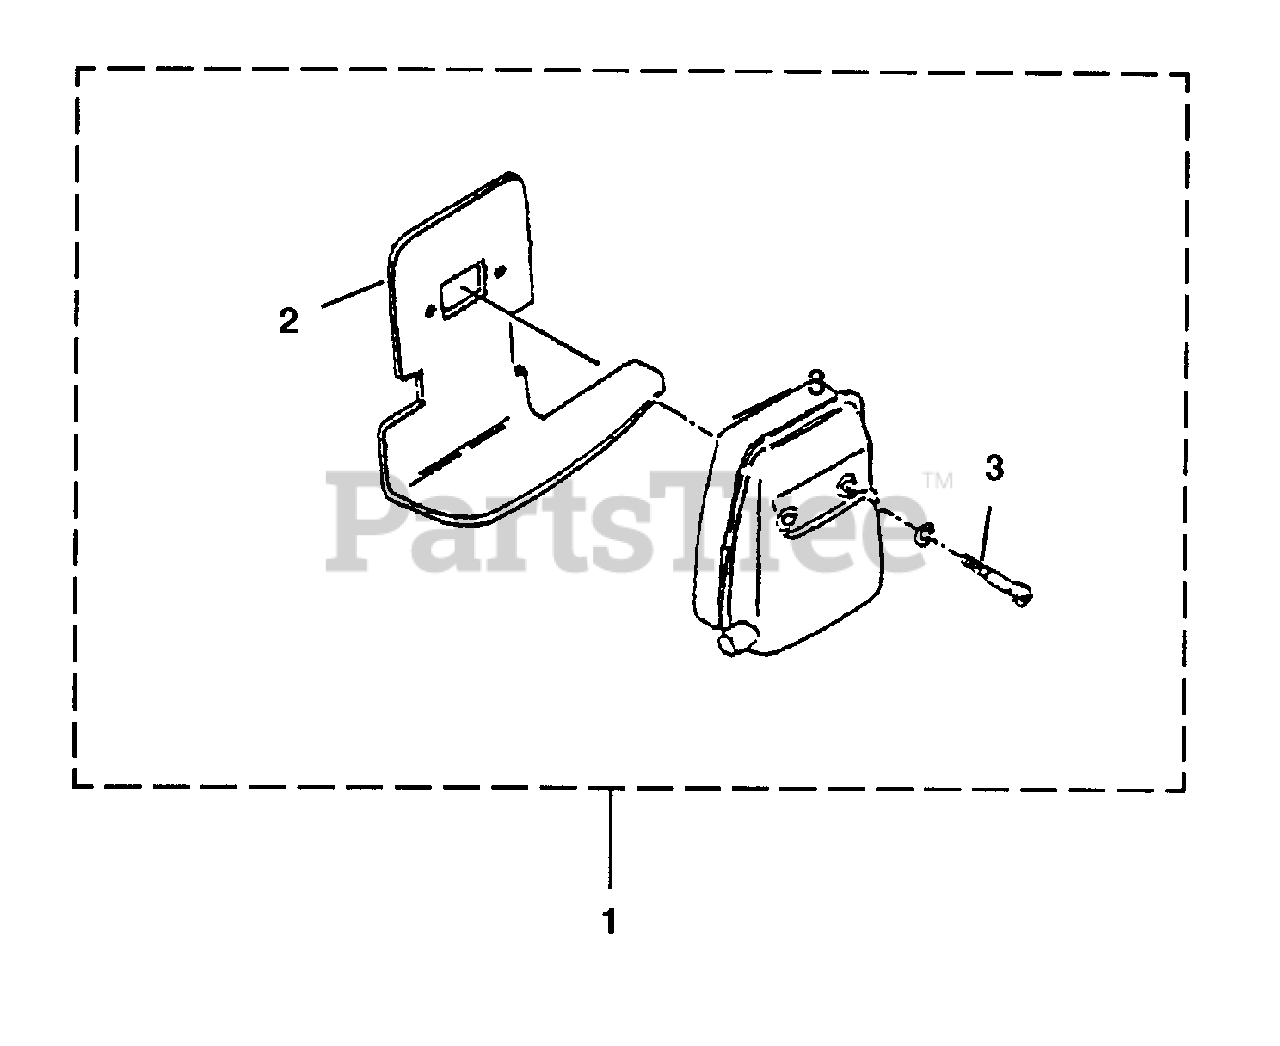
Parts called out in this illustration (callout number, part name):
1	MUFFLER ASSEMBLY
2	GASKET-Muffler
3	SCREW-Socket Hd (M5 x 45)
